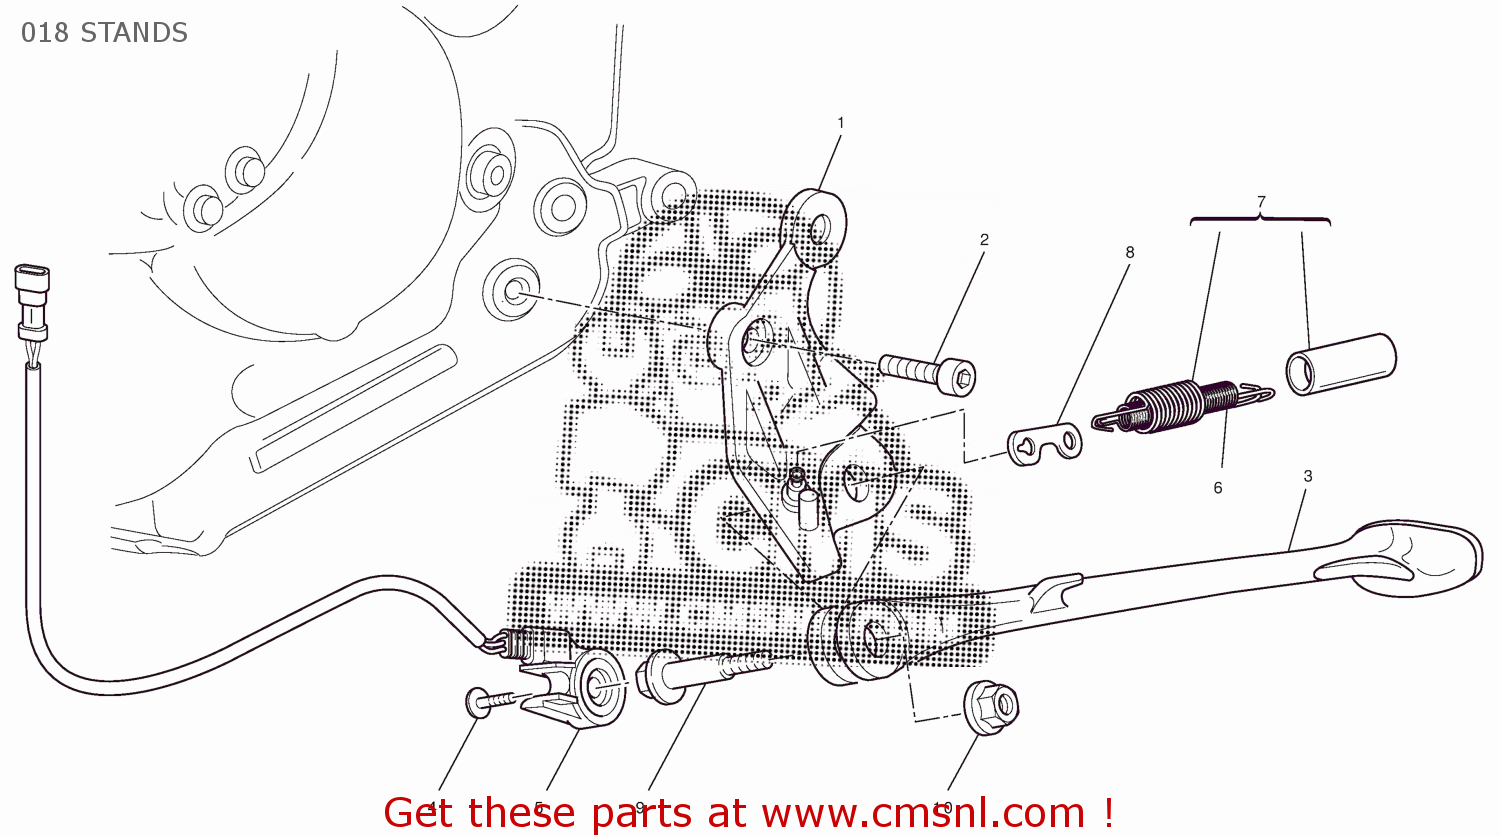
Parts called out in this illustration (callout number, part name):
1	BRACKET, SIDE STAND
2	SCREW TCEI M10X25
3	SIDE STAND
4	SCREW
5	SWITCH, STAND
6	INNER SPRING
7	OUTER SPRING
8	LINK, SIDE STAND
9	SHAFT, STAND
10	NUT M10X1.25
